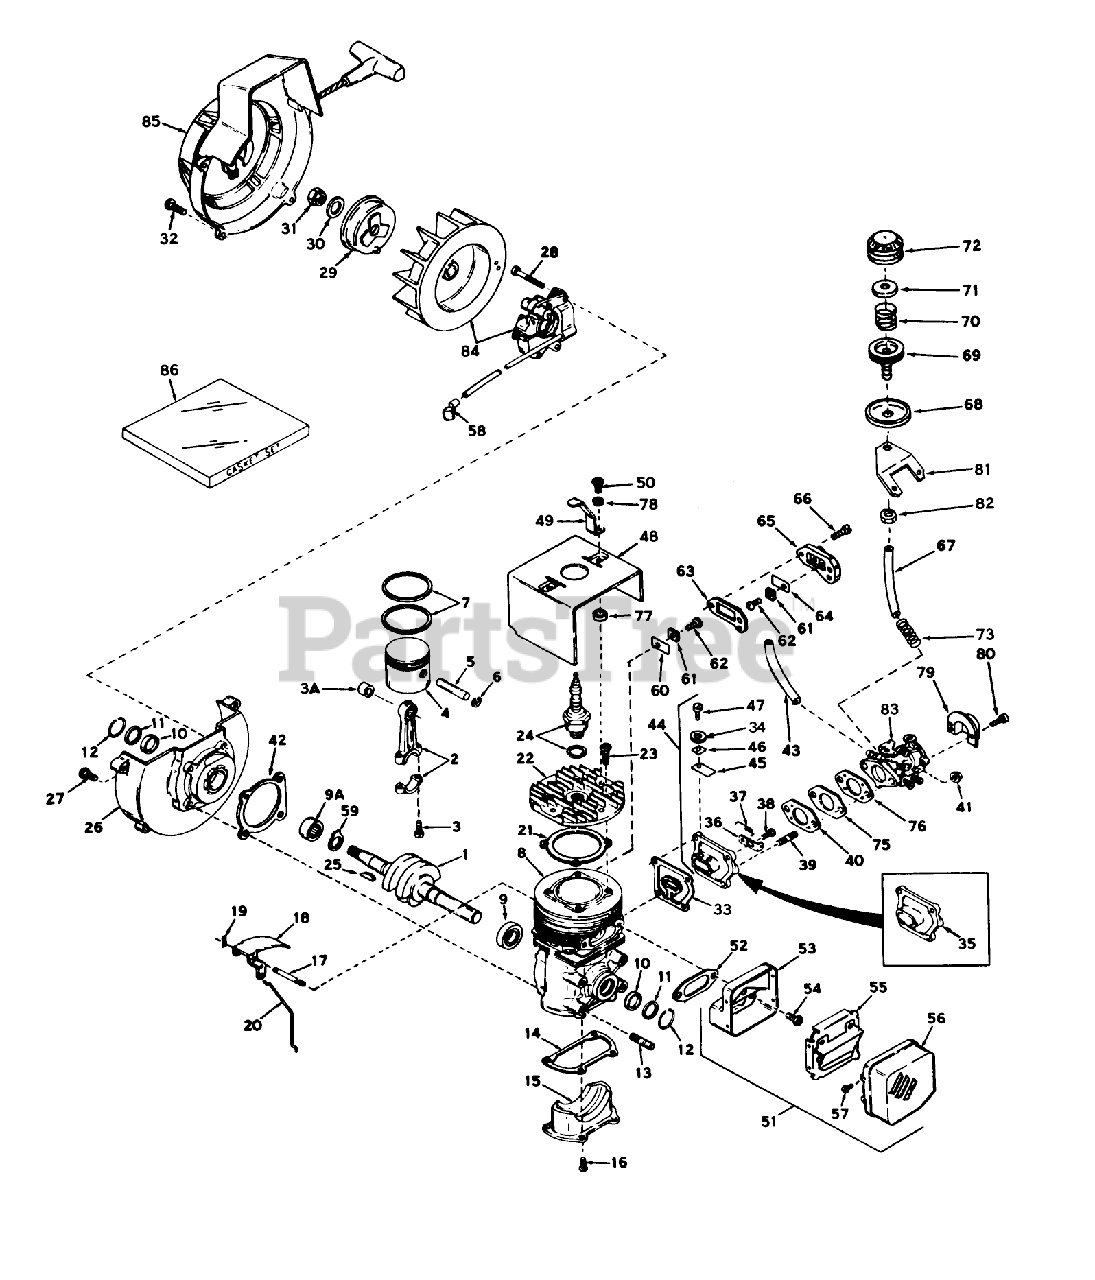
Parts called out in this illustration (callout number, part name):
1	Crankshaft
2	Rod Assembly, Connecting (Incl. Nos. 3 3A)
3	Bolt-Rod, Connecting
3A	Bearing-Cartridge
4	Piston
5	Pin, Piston
6	Ring-Retaning
7	Ring Set
8	Block Assy., Cylinder (Incl. Nos. 9, 10 thru 13 17)
9	Bearing Ball
9A	Bearing-Cartridge
10	Seal, Crankshaft
11	Retainer, Crankshaft Seal
12	Spring, Crankshaft Seal
14	Gasket, Cover
15	Plate, Cover
16	Screw (T-25, 10-24 x 1/2)
17	Shaft, Air Vane
18	Vane Assy, Air
19	Clip,Air Vane
20	Link Governor
21	Gasket, Cylinder Head
23	Screw (T-30, 1/4-20 x 3/4)
24	Plug, Spark (J17LM)
25	Key, Woodruff
26	Base Assembly, Shroud (Incl. #9A-12)
27	Screw
28	Screw
29	Cup, Starter
30	Washer, Flat
31	Nut, Flywheel
32	Screw (T-30, 1/4-20 x 3/4)
33	Gasket, Port
34	Washer, Flat
35	Adapter, Cover
36	Lever, Adjusting
37	Spring, Adjusting Lever
38	Screw
40	Gasket, Carburetor 1/8" thick)
41	Locknut
42	Gasket, Shroud Base
43	Line-Fuel (8.62)
44	Plate Assy. Reed(Incl. Nos. 45, 46 47j (Type 1450D)
45	Reed Type 1450B
46	Stop, Reed Type 1450B
47	Screw, Diaphragm Cover
48	Shroud, Cylinder
49	Lever, Stop
50	Screw
51	Muffler Assembly (Incl. #53-57)
52	Gasket-Muffler
53	Base-Muffler
54	Screw
55	Baffle, Muffler
56	Cover, Muffler
57	Screw
58	Terminal, Lead wire
59	Washer, Thrust
60	Reed, Compression Release
61	Plate, Reed Hold Down
62	Screw
63	Gasket, Compression Release
64	Reed, Compression Release
65	Cover, Compression Release
66	Screw
67	Line, Primer
68	Retainer, Primer Bulb
69	Body, Primer
70	Spring, Primer Bulb
71	Washer, Primer Bulb
72	Bulb, Primer
73	Spring, Primer line support
75	Spacer
76	Gasket, Carburetor (1/16"thick)
77	Spacer
78	Washer
79	Baffle-Carburetor
80	Screw
81	Mounting Bracket, Primer
82	Hex nut
83	Carburetor
84	BRACKET S
85	Shroud Starter Assy.
86	Gasket Set
